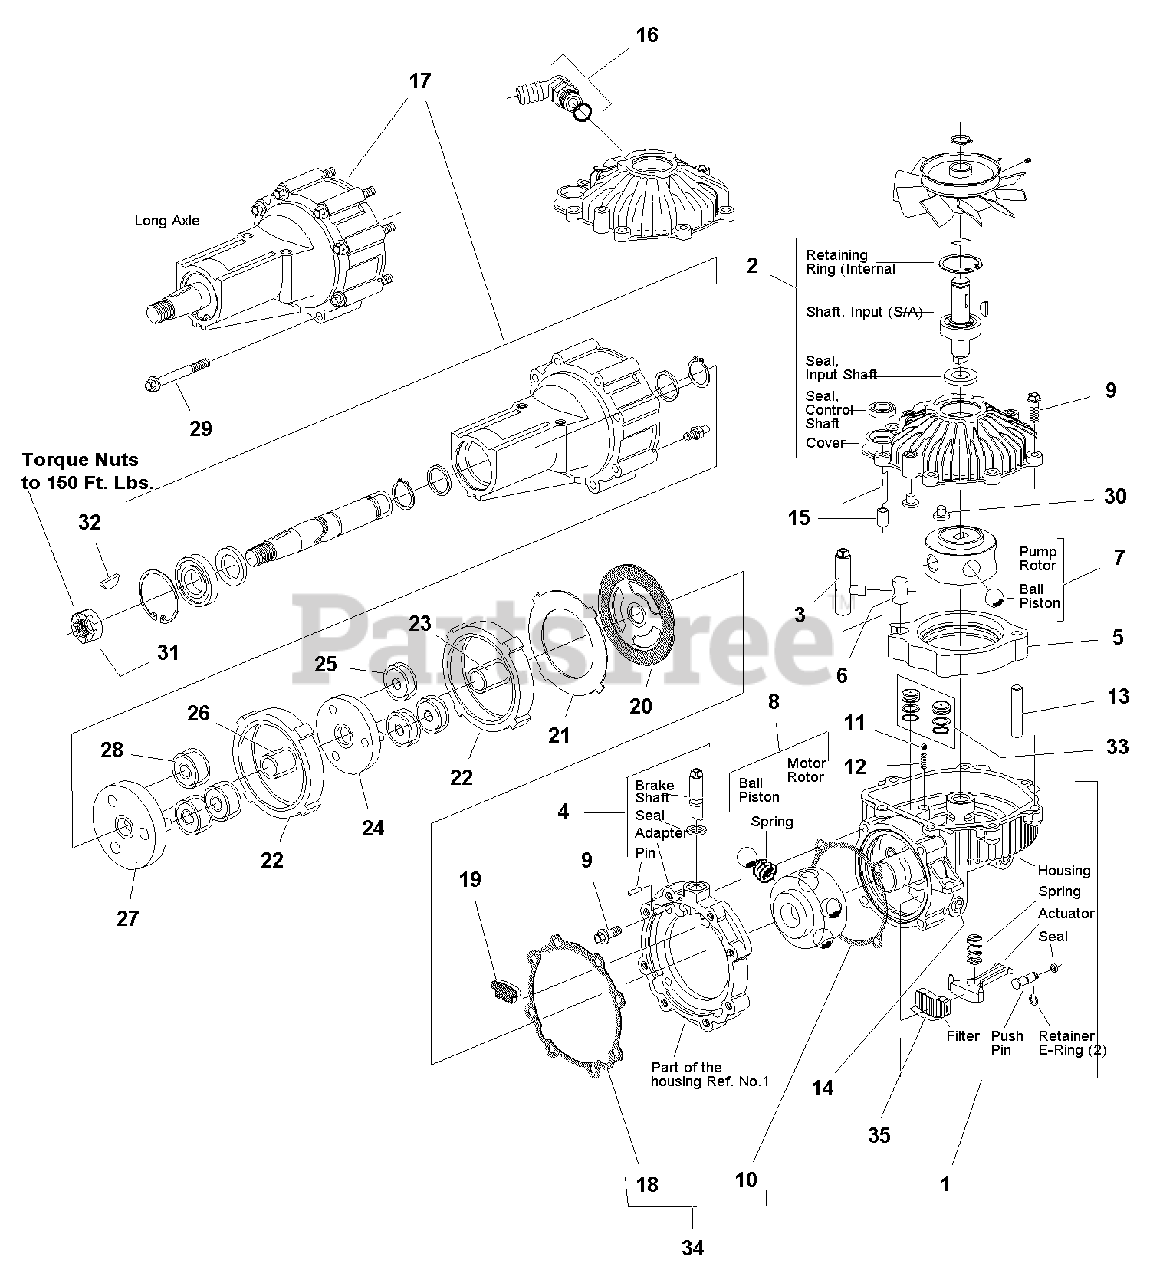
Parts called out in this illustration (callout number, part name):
1	HOUSING ASSEMBLY, (Includes Housing, Filter, Actuator. Spring, E-Ring Retainer, Actuator Pin, & Seal)
2	COVER ASSEMBLY, Input (Includes Retaining Ring, Shaft, Input Shaft Seal, & Control Shaft Seal)
3	SHAFT, Control
4	ADAPTER/BRAKE ASSEMBLY (Includes Dowel Pin, Brake Shaft, Adapter, & Seal)
7	ROTOR/BALL, Pump
8	ROTOR/BALL/SPRING, Motor
9	CAPSCREW, Self Tap
11	BALL (Grade 200)
14	PLUG, Socket Pipe
15	BUSHING, Dowel
16	BARB FITTING (Includes O-Ring), for 7/8 Hose
16	BARB FITTING (Includes O-Ring), for 3/8 Hose
17	AXLE HOUSING ASSEMBLY, Tapered (Includes Axle Shaft, Internal Retaining Ring, Housing, Radial Lip Seal, Ball Bearing, External Retaining Ring, Thrust Washer, & Magnet)
18	GASKET, Axle Housing
19	PAD, Friction
20	PLATE, Reaction
21	PLATE, Backup
22	GEAR, Ring 54T
23	GEAR, First, 18 Teeth
24	18T PRIMARY CARRIER
25	GEAR, First, 18 Teeth
26	18T SUN GEAR, Second
27	SECONDARY CARRIER
28	GEAR, Second, 18 Teeth
29	CAPSCREW, Hex Flange, 1/4-20
30	GASKET, Filter Base
31	NUT, Slotted Hex (Tapered Shaft)
32	KEY, Woodruff (Tapered Shaft)
33	PISTON
